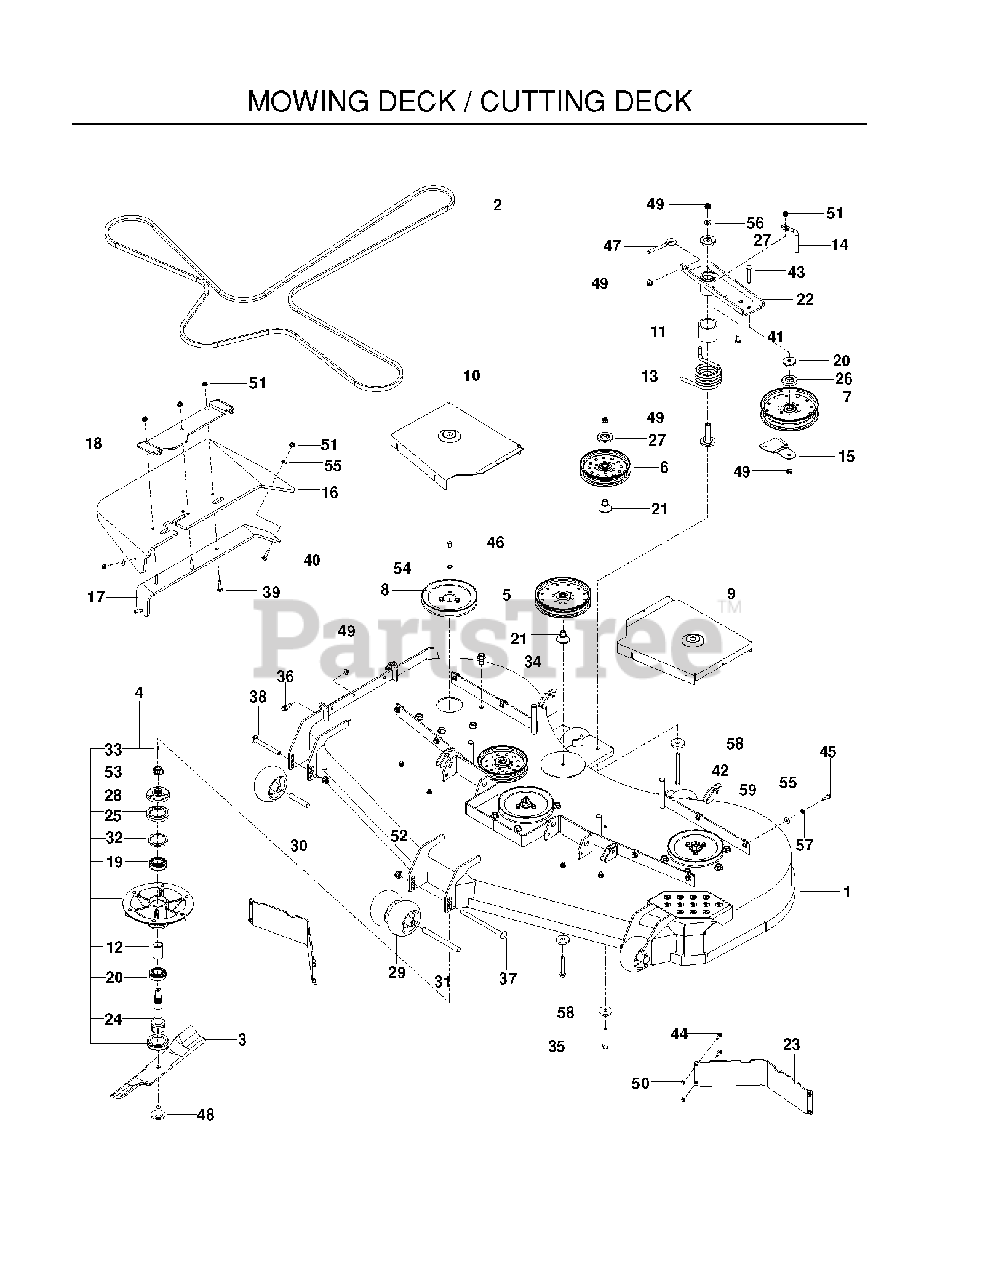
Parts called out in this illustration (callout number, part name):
1	DECK W/SAFETY DECALS 72"
2	BELT, "B", 201
4	SPINDLE ASM. 10"
5	PULLEY - 7" NARROW
6	PULLEY IDLER, 6" NARROW
7	PULLEY - IDLER 7"
8	PULLEY - 7.50
9	SHIELD, 72 RT
10	SHIELD BELT LH 72 BLUE
11	SPACER, IDLER PIVOT
12	SPACER - BEARING
13	SPRING, TORSION, IDLER
14	BELT KEEPER
15	BELT GUIDE, BLK
16	CHUTE, DISCHARGE 60-72
17	BRKT - CHUTE SUPPORT BLACK
18	BRKT - CHUTE MTG BLACK
19	BEARING - 206KRR8
20	BEARING, IDLER ARM
21	BEARING, IDLER PIVOT
22	ASSY, IDLER ARM, PZ
23	BAFFLE, DIVERTER 72" BLACK
24	SHAFT - SPINDLE
25	CUP - DEBRIS
26	SHIELD, DUST
27	DUST SHIELD
28	HUB - PULLEY
29	ROLLER, GAUGE .635 BORN
30	TUBE, ROLLER AXLE
31	TUBE, ROLLER AXLE LONG
32	V-RING, 55MM
33	ZERK
34	HHFS 1/2-13 X 1 GR5 ZD
35	HHFS 3/8-16 X 2 3/4
36	HHFS 3/8-16 X 1 GRD 5 ZD
37	RHSNB 1/2-13 X 8 GR5 ZD
38	RHSNB 1/2-13 X 4.75 GR5 ZD
39	RHSNB 5/16-18 X 1-1/2 GR 5 ZD
40	BOLT, CARRIAGE 5/16X1-1/4
41	RHSSNB 5/16C X 1.0
42	HCS 3/8-16 X 4-1/2 GR 8 ZD
43	CARRIAGE BOLT 3/8-16 X
45	HCS 5/16C X 1
46	HCS 5/16-18 X 1/2 GR 5 ZD
47	EYE BOLT, 3/8 X 4"
48	BLADE BOLT/WASHER
49	NUT 3/8-16 HEX FLG NYLOC ZD
50	NUT 1/4-20 NYLOC
51	5/16-18 NYLOC FLANGE NUT
52	NUT, 1/2-13 HEX FLG NYLOC ZD
53	NUT FLANGE 3/4-16
54	WASH 5/16 DISC SPRING ZD
55	WASHER 5/16 FLAT
56	WASHER, 3/8 THICK
57	WASHER 5/16 LOCK
58	SPINDLE WASHER
59	U-CLIP 5/16-18 NUT RETAINER
